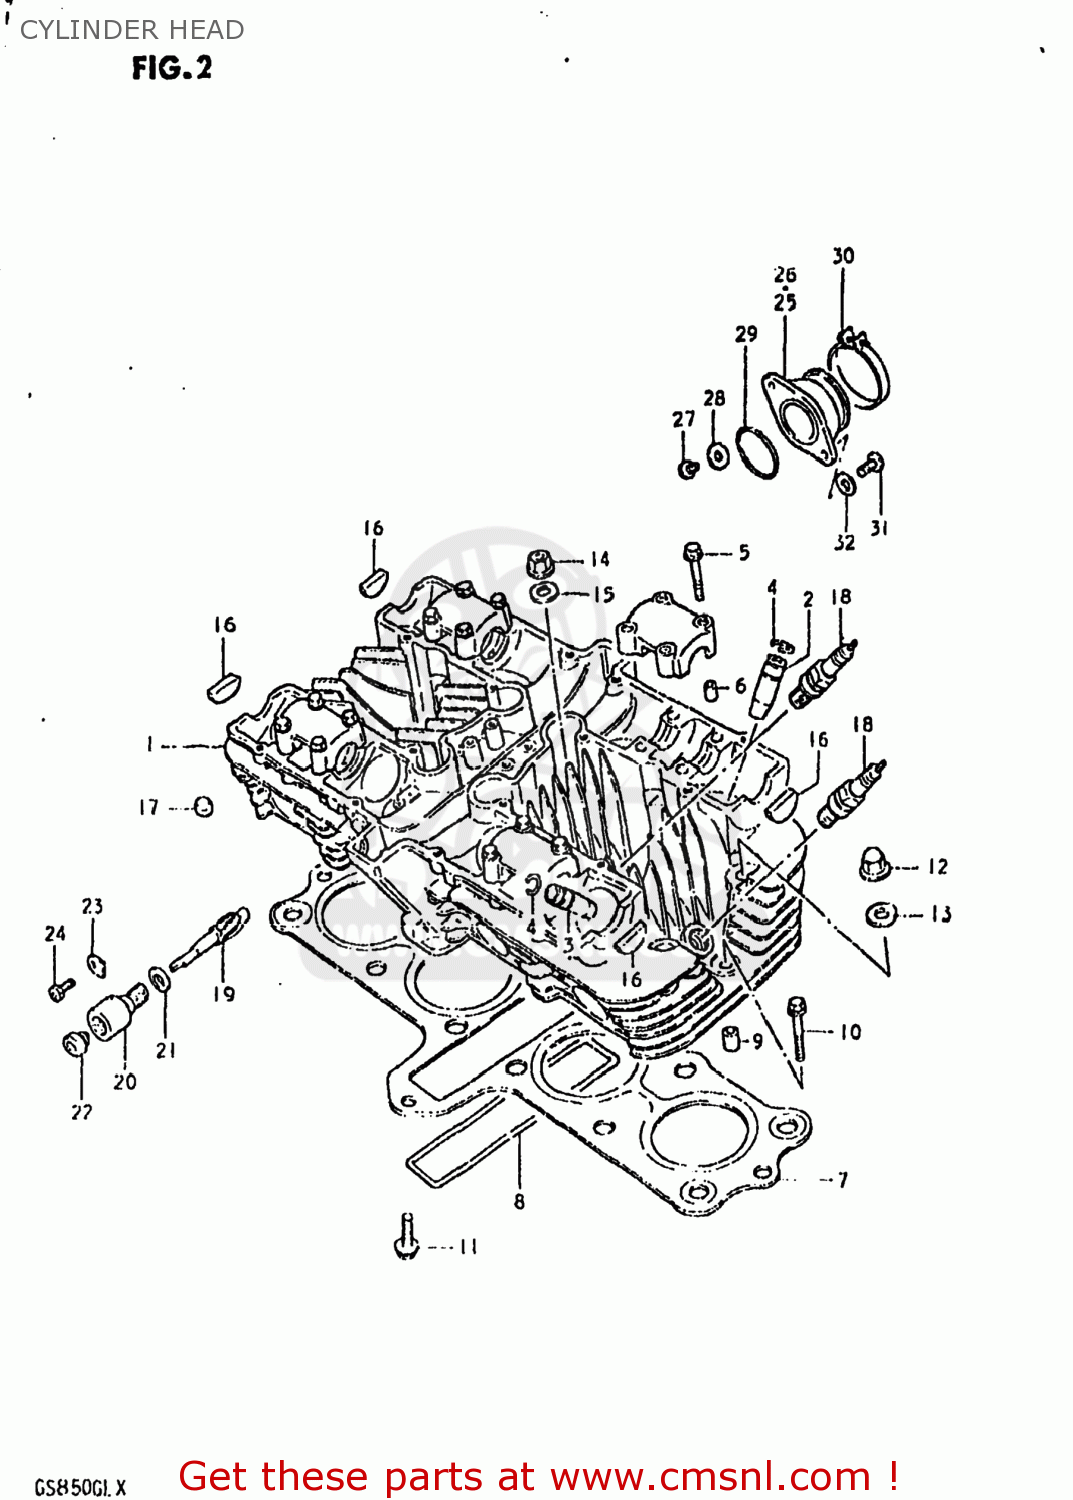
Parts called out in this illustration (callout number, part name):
1	HEAD ASSEMBLY,CYLINDER
2	GUIDE,INTAKE VALVE
3	GUIDE,EXHAUST VALVE
4	RING,SNAP
5	BOLT(6X39)
6	PIN(6.2X8X11)
7	GASKET,CYLINDER HEAD (MCA)
8	O RING(D:3,ID:26X157)
9	PIN
10	BOLT,UNDER
11	BOLT
12	NUT
13	GASKET(10.5X22X2) (NAS)
14	NUT
15	WASHER(10.5X22X2.3)
16	PLUG
17	PAD
18	SPARK PLUG
19	GEAR,TACHOMETER DRIVEN
20	SLEEVE,TACHOMETER DRIVE
21	SEAL,TACHOMETER DRIVEN
22	SEAL,OIL(5X12X8)
23	PLATE,TACH DRIVE GEAR SLEEVE
24	SCREW(5X12)
25	PIPE,INTAKE,R
26	PIPE,INTAKE,L
27	BOLT
28	GASKET(5.3X9.3X1.2) (NAS)
29	O-RING
30	CLAMP
31	SCREW
32	WASHER
